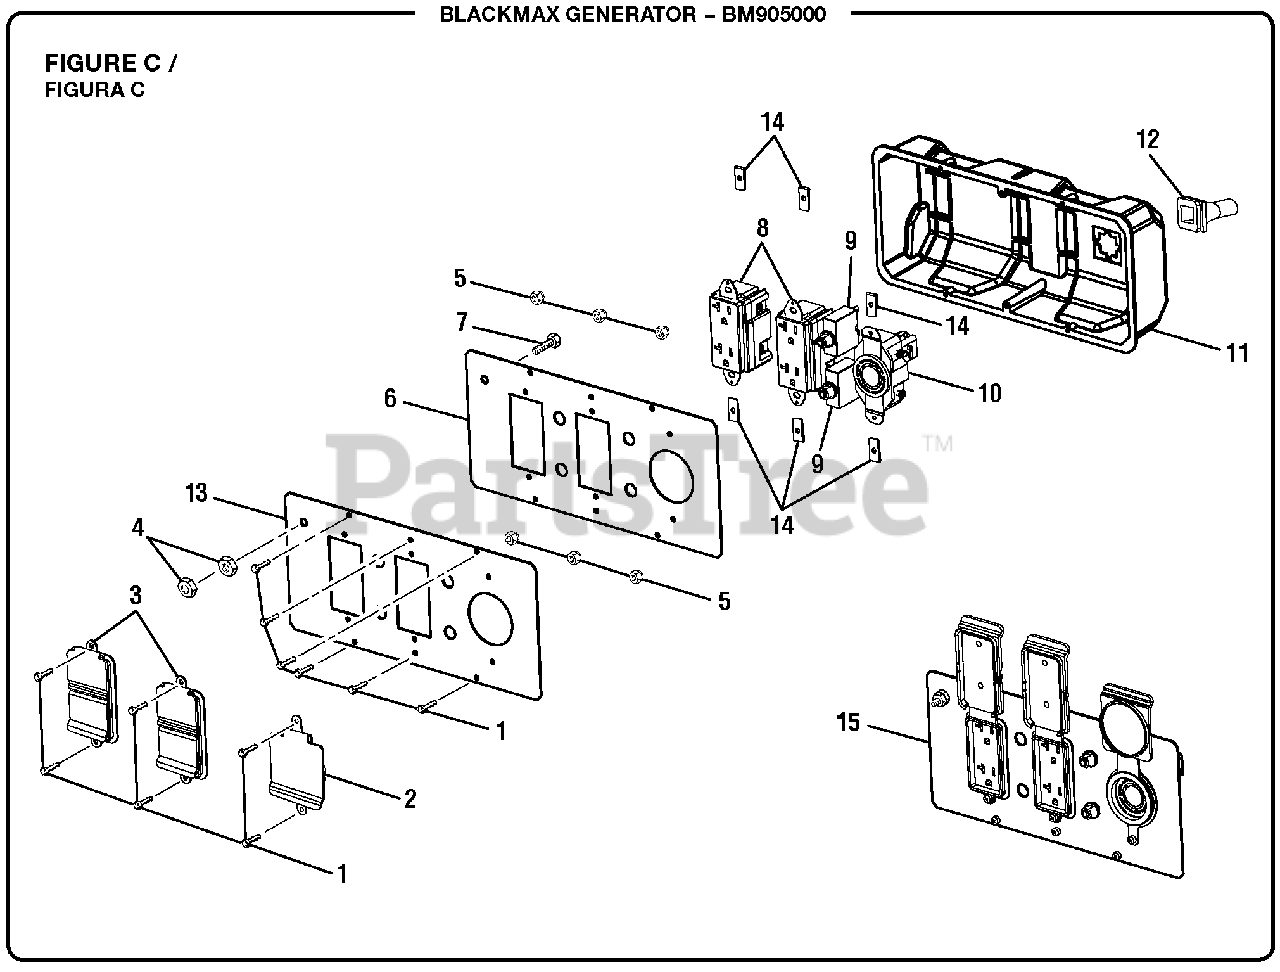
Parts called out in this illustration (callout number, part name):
1	Screw (6-20 x 3/8 in.)
2	Outlet Cover (240 V)
3	Outlet Cover (120 V)
4	Hex Nut (1/4-20)
5	Nut (M6-32)
6	Cover Plate
7	Screw (1/4-20 x 5/8 in., Hex Hd.)
8	Duplex Receptacle (120 V)
9	Circuit Breaker (20 A, 125 V)
10	Twist Lock Receptacle (120/240 V, 20 A)
11	Rear Control Panel
12	Rubber Boot
13	Control Panel Label
14	Speed Nut
15	Front Panel Assembly
